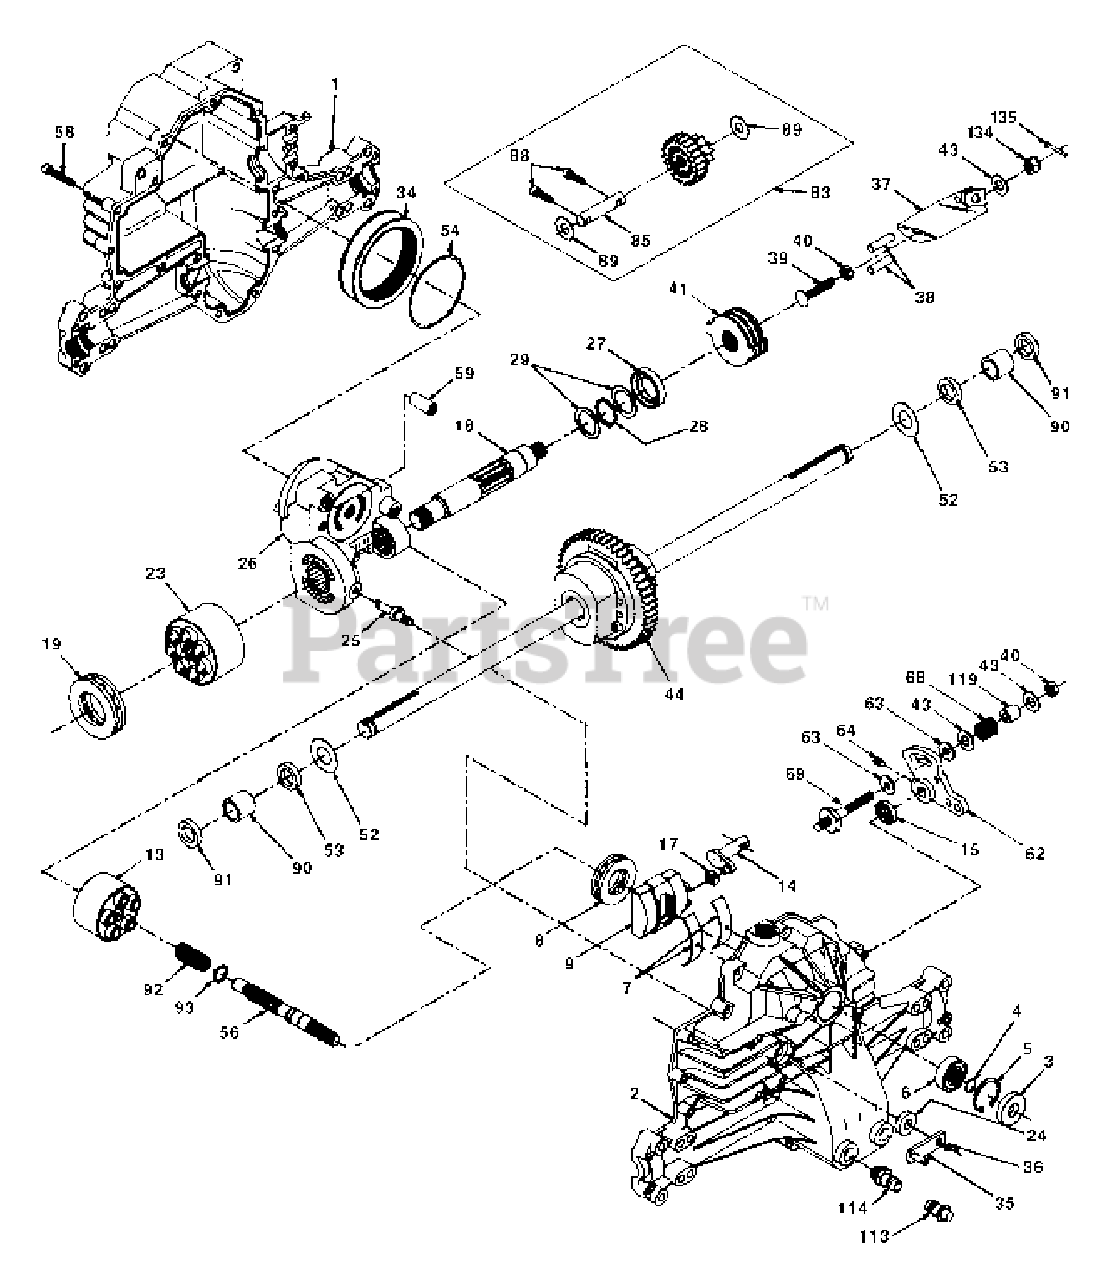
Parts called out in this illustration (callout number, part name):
1	Housing, Lower
2	Assembly, Upper Housing
4	Ring, Wire Retaining
5	Ring, Retaining
6	Bearing, Shaft Ball
7	Bearing, Cradle
8	Bearing, Thrust 30 x 52 x 13
9	Swashplate, Variable
13	Block, Cylinder Assembly
14	Arm, Trunnion
17	Guide, Slot
18	Shaft, Motor
19	Bearing, Thrust 42 x 68 x 16
23	Block, Cylinder Assembly
24	Seal, Lip 10 x 25 x 7
25	Actuator, Bypass
26	Center Section Assembly Kit
27	Seal, Lip 26 x 42 x 8
28	Ring, Retaining
29	Washer 26 x 35 x 1
34	Oil Filter Element
35	Arm, Bypass
36	Ring, Retaining
37	Arm, Actuating
38	Pin, Actuating
39	Bolt 5/16-24 x 1-3/4
40	Locknut, Hex 5/16-24 UNJC
41	Brake Rotor/Stator Kit
43	Washer 7/16 x 7/8 x .060
44	Differential Assembly
52	Washer 3/4 x 1.5 x .03
53	Seal .75 x 1.25 x .250
54	O-Ring .103 x 2.987 ID
56	Shaft, Input
58	Bolt 1/4-20 x 1.38
59	Pin .5 OD x .43 ID x .750
62	Arm, Control
63	Puck, Dampener
65	Bolt #8-32 x .875
69	Socket Set Screw
83	Jack Shaft Assembly
85	Jack Shaft
90	Sleeve Bearing
91	Seal, Wiper
92	Spring, Block
93	Washer, Block Thrust
95	Strap, Locking
113	Cap, Vent Assembly
114	Fitting, O-Ring Assembly
119	Spacer
121	Jam Nut 5/16-24
